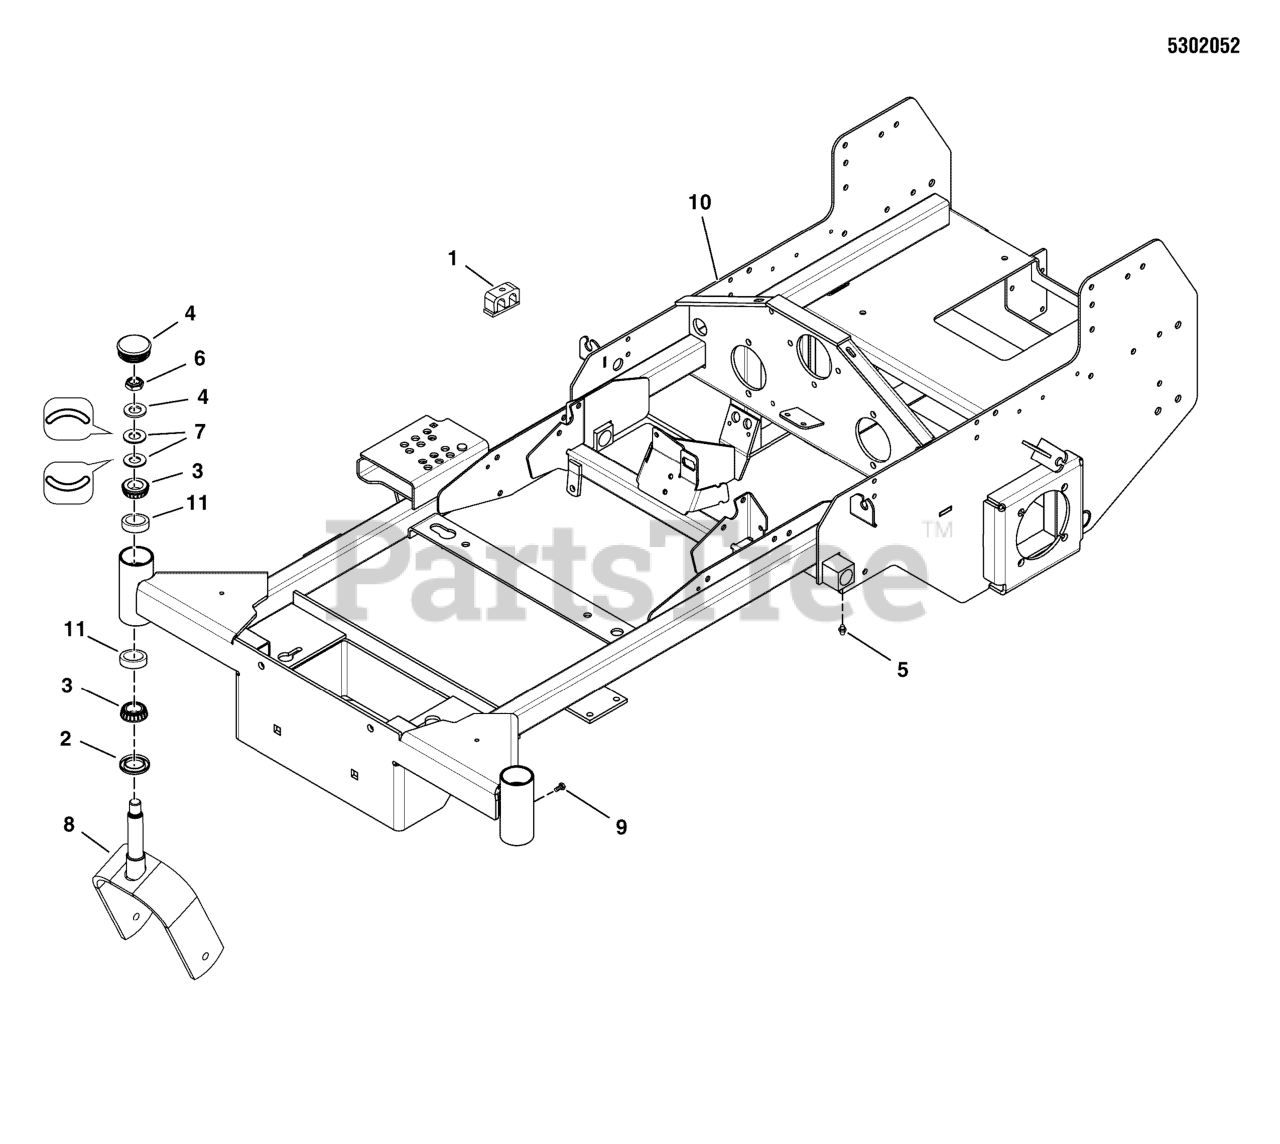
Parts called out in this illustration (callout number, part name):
1	CLAMP, 5/16, DOUBLE, WIRE & TUBE
2	SEAL, GREASE
3	BEARING, TAPERED ROLLER, 1
4	CAP, GREASE, LOW PROFILE
5	GREASE FITTING, 45 DEGREE
6	NUT, 3/4-16, HEX JAM NYLON LOCK
7	WASHER, BELLEVILLE - 1.500 X .755
8	WELD, CASTER YOKE - RED
9	BOLT, 1/4-28 X 1/2, GD5 YZ
11	BEARING CUP
